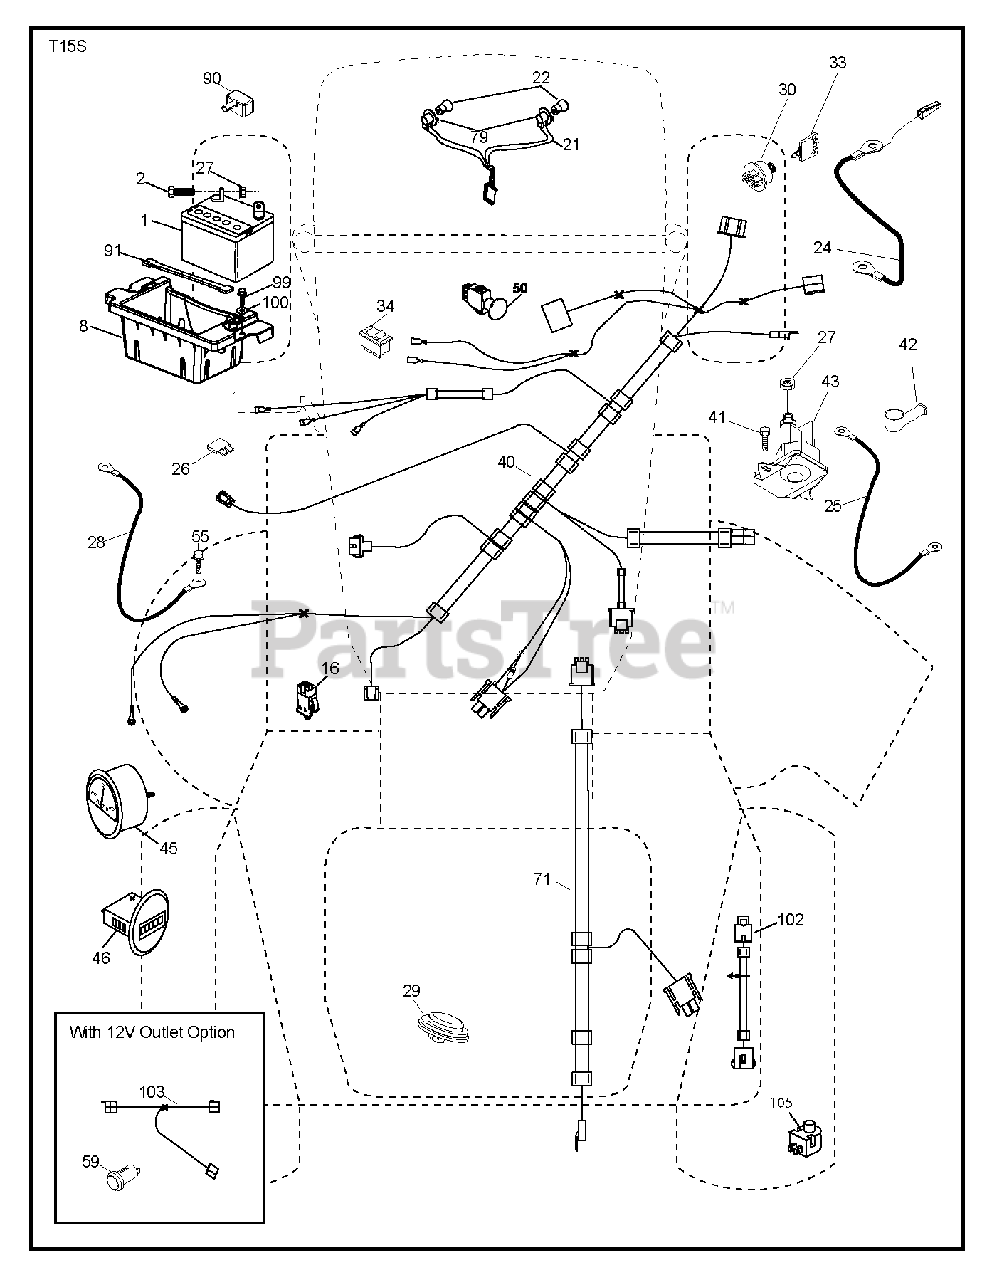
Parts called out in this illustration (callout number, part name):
2	BOLT LT
8	BOX, BATTERY MOUNT
16	SWITCH INTERLOOK PUSH-IN
21	HARNESS SOCKET LIGHT
22	LIGHTBULB
24	CABLE.BTRY.PSWRE.DSH.S
25	CABLE STARTER
26	FUSE 20AMP
28	CABLE GROUND 6 GA 21" 90T BLK
29	SWITCH.SEAT.DELTA.OPC.
30	IGNITION SWITCH
33	KEY/CHAIN.BLISTER.PACK.GEN.CE
34	SWITCH LT
40	HARNESS IGN. DASH
43	SOLENOID.W/BRASS.PLUNG
45	AMMETER.ROUND.SNAPIN
46	HOURMETER.ROUND.SNAPIN
50	PTO SWITCH
71	HARNESS-CHASSIS SUB
79	BULB HOLDER ASM.
90	COVER.TERMINAL.BATTERY
91	STRAP, BATTERY MOUNT
99	SCREW HEXWSHR 1/4-20X3/4
102	HARNESS PIGTAIL PCH TEX ROS
105	REVERSE SWITCH
